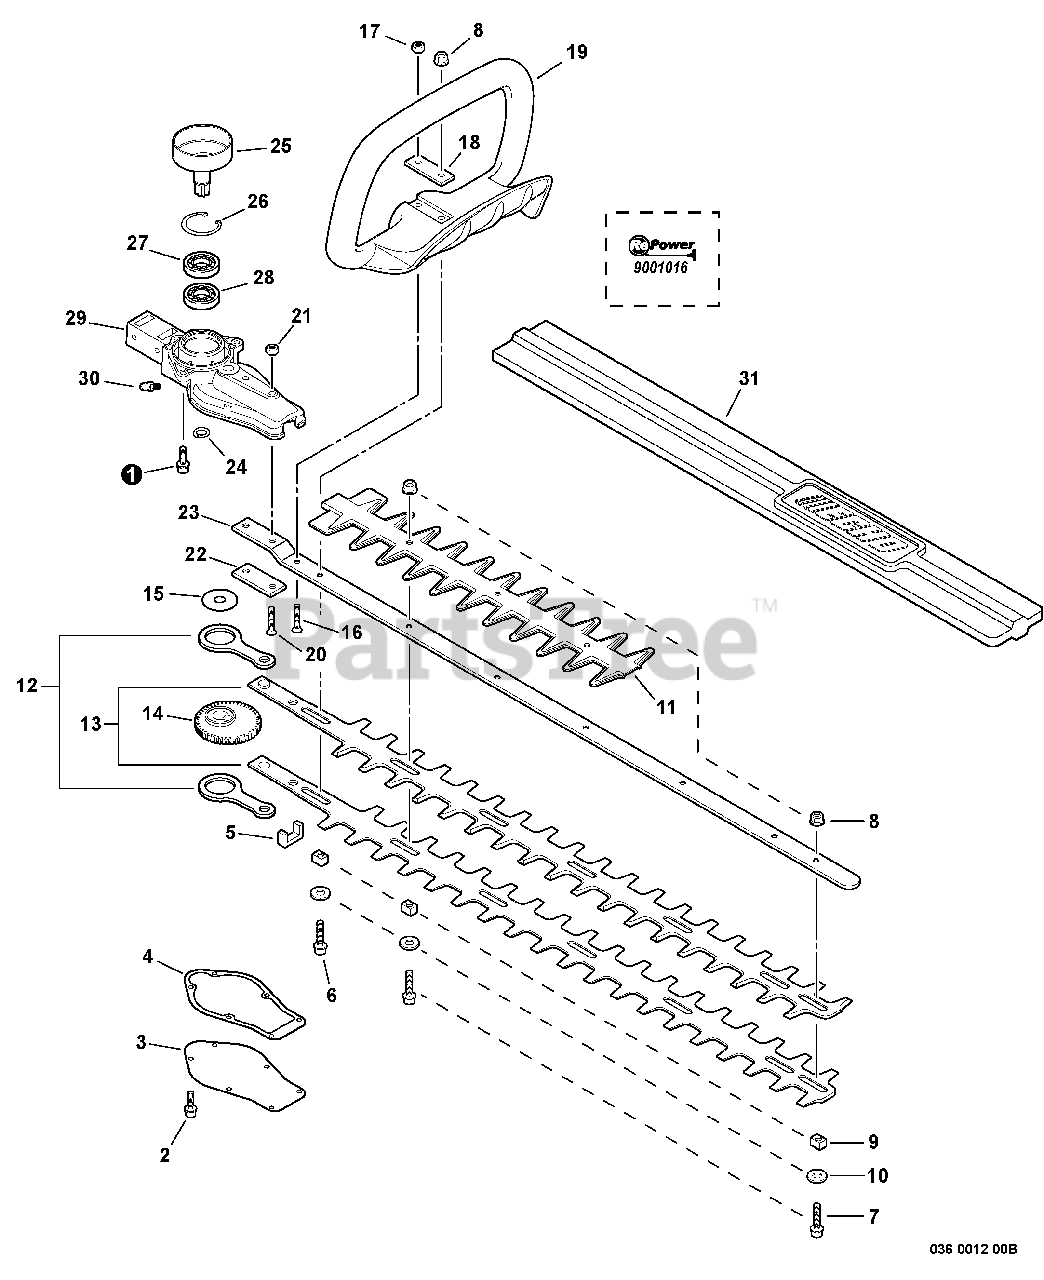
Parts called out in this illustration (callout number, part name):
1	SCREW - 5X20
2	SCREW - 4X10
3	LID, GEAR CASE
4	GASKET, GEAR CASE
5	SEAL, FELT
6	SCREW - 5X40
7	SCREW - 5X20
8	LOCKNUT - 5
9	GUIDE, BLADE
10	WASHER - 6
11	SHIELD, BLADE
12	ROD, CONNECTING
13	BLADE - 24" (60cm)
14	GEAR - DRIVE
16	SCREW - 5X30
17	LOCKNUT - 5
19	HANDLE - FRONT
20	SCREW - 6X25
21	LOCKNUT - 6
23	SUPPORT, BLADE
24	RING, RETAINING - 14
25	DRUM, CLUTCH
26	RING, RETAINING - 35
27	BEARING, BALL - 6202
28	BEARING, BALL - 6202
29	CASE, GEAR
30	FITTING, GREASE
31	COVER, BLADE - 24" (60cm)
32	RePower GEAR CASE/BLADES KIT
